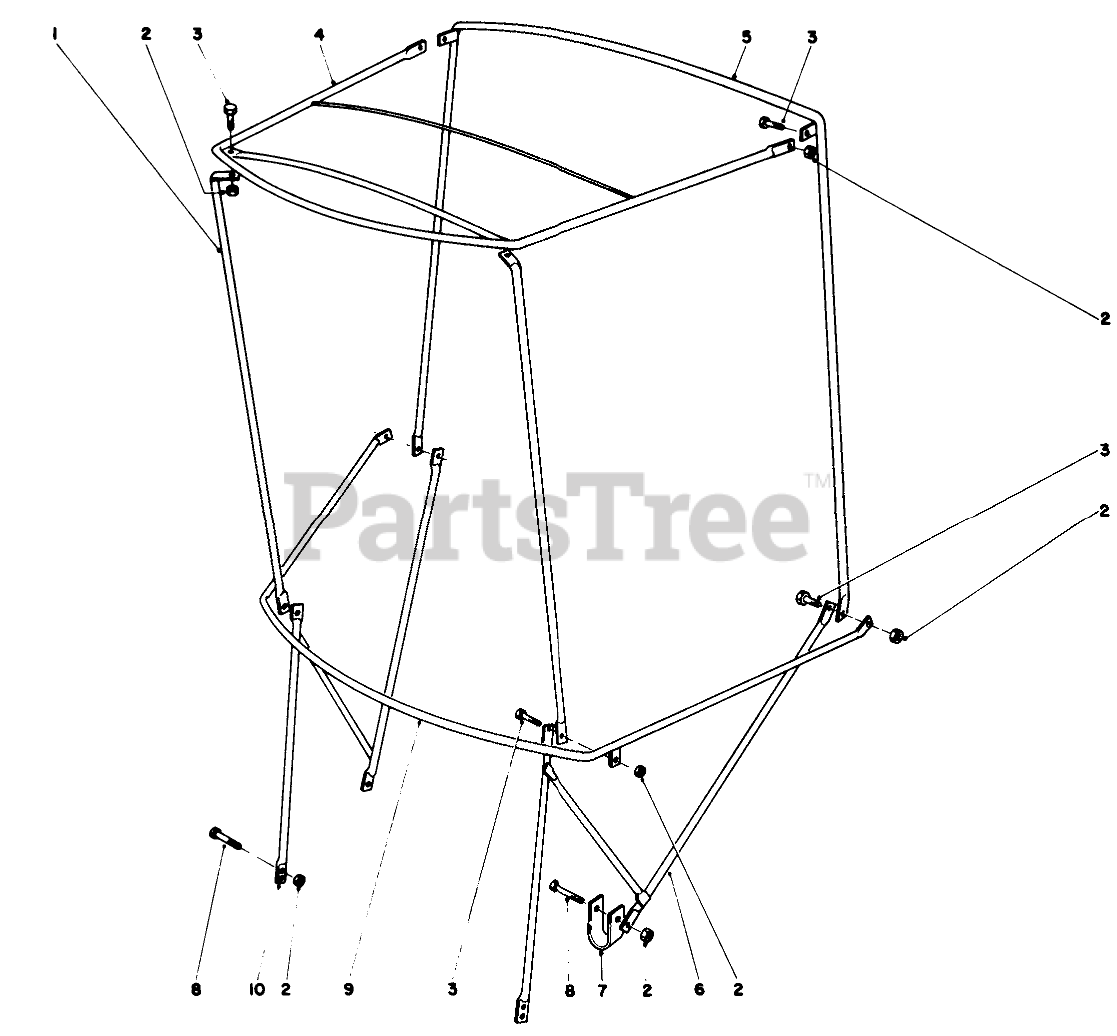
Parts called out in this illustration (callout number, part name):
2	NUT-HEX, SIDE DEFORM
3	SCREW-HH
4	FRAME-TOP
5	BOW-VERTICAL, REAR
6	ATTACHING BRKT L
7	U CLAMP
8	SCREW-HH
9	BOW-CURVED
10	ATTACHING BRKT R
